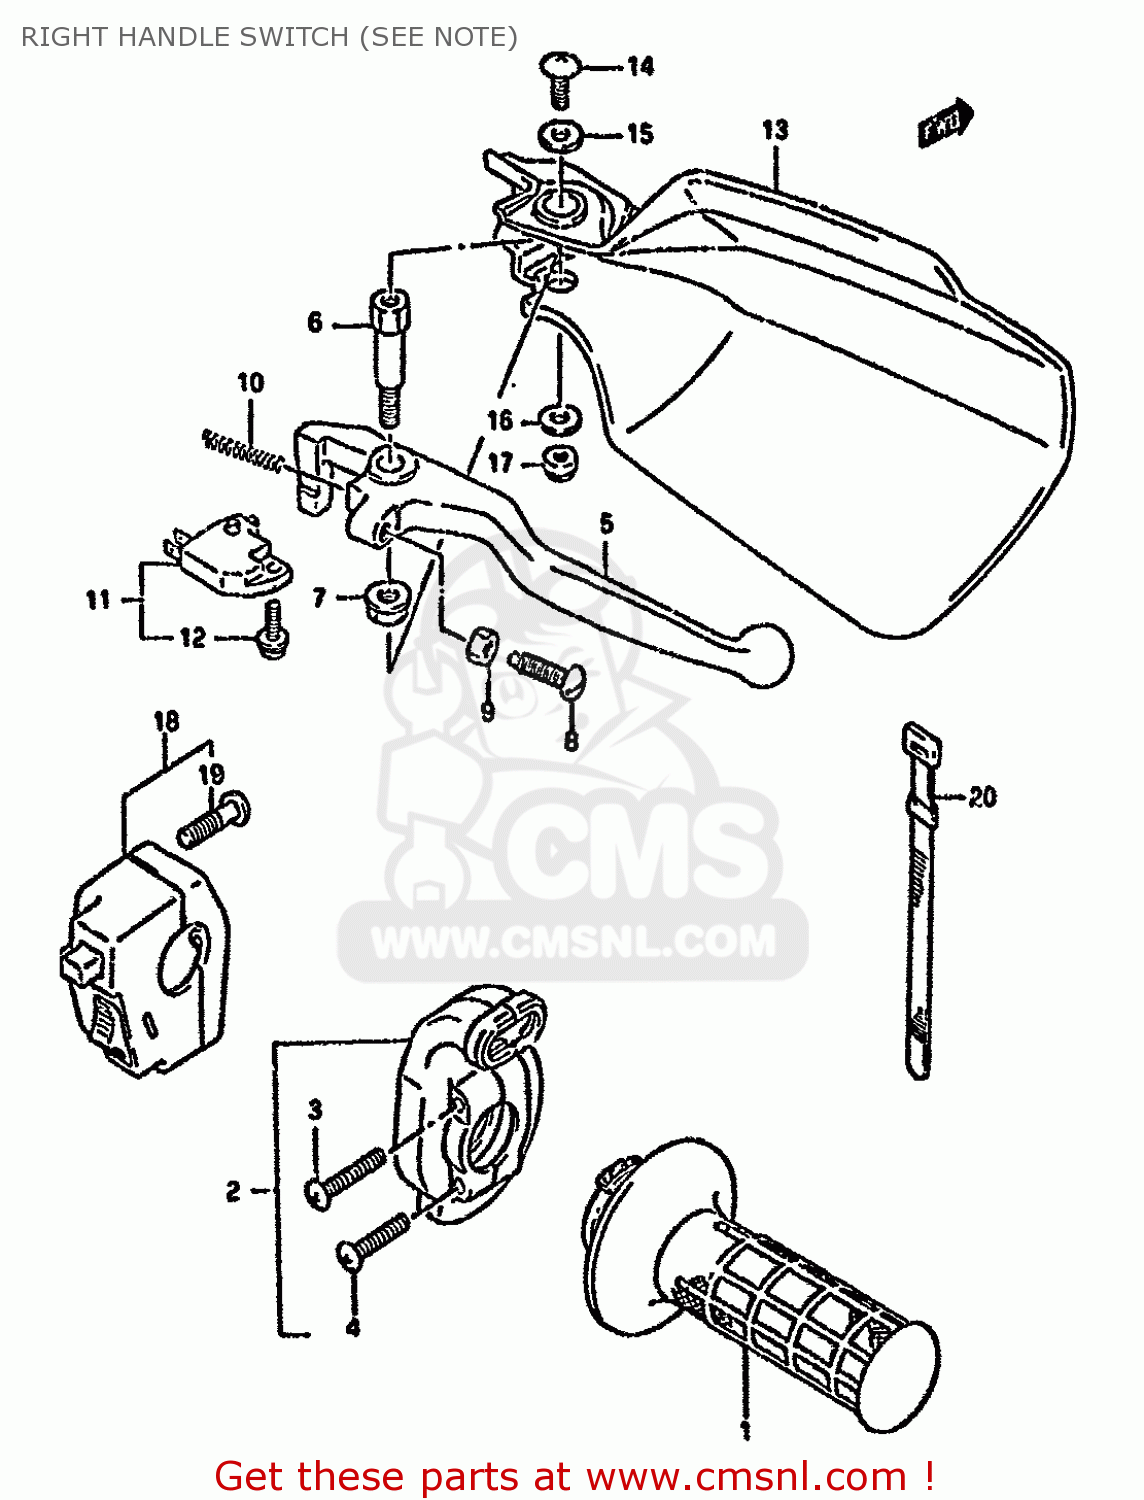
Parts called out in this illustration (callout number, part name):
1	GRIP,THROTTLE
2	CASE ASSY,THROTTLE
3	SCREW(5X25)
4	SCREW 5X20
5	LEVER,BRAKE
6	BOLT,BRAKE LEVER PIVOT
7	NUT 6MM
8	BOLT,ADJUST
9	NUT ,5MM
10	SPRING,RETURN
11	SWITCH ASSEMBLY,STOP
12	SCREW
13	COVER,KNUCKLE,R
14	SCREW(5X10)
15	WASHER(5.5X16X1.5)
16	WASHER (6.5X17X1.6)
17	NUT 6MM
18	SWITCH ASSY,HANDLE,R
19	SCREW(5X25)
20	CLAMP(L:120)
